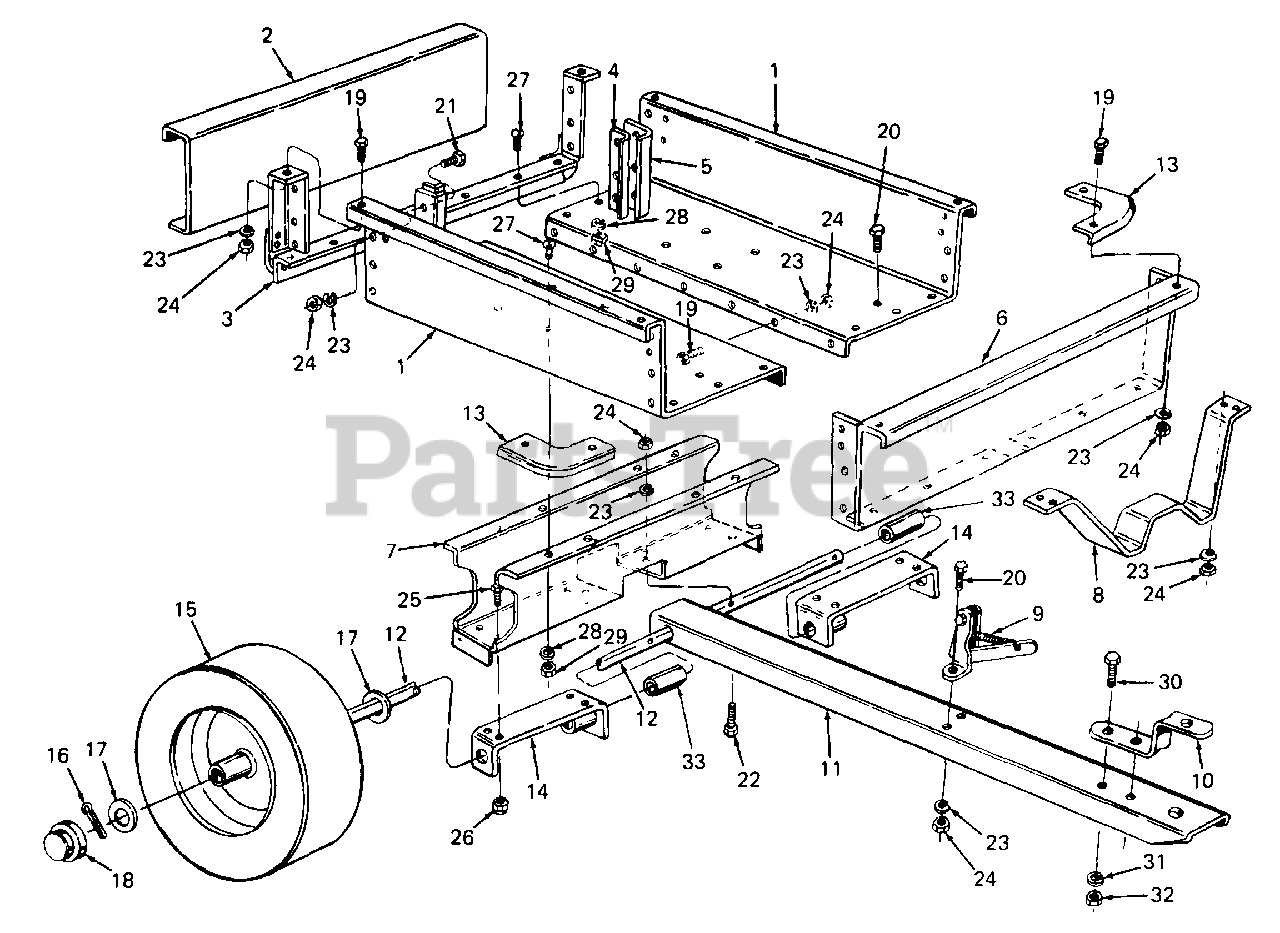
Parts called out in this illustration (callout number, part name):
5	Guide, Tailgate - Outside
17	Washer, Flat, 1.03 ID
18	Cap, Hub
19	Screw, Hex Cap, 1/4-20 X .50 Lg GR5
20	Screw, Hex Cap, 1/4-20 X .62 Lg
21	Screw, Hex Cap, 1/4-20 X .75 Lg
22	Screw, Hex Cap, 1/4-20 X 1.75 Lg
23	Washer, Lock, 1/4
24	Nut, Hex, 1/4-20
25	Screw, Hex Cap, 5/16-18 X .75 Lg GR5
26	Nut, Hex Center Lock, 5/16-18 GR5
27	Screw, Truss Mach Hd, 5/16-18 X .75 Lg
28	Washer, Lock, 5/16
29	Nut, Hex, 5/16-18
30	Screw, Hex Cap, 3/8-16 X 1.0 Lg GR5
31	Washer, Lock, 3/8
32	Nut, Hex, 3/8-16 GR5
33	Spacer, Tube
